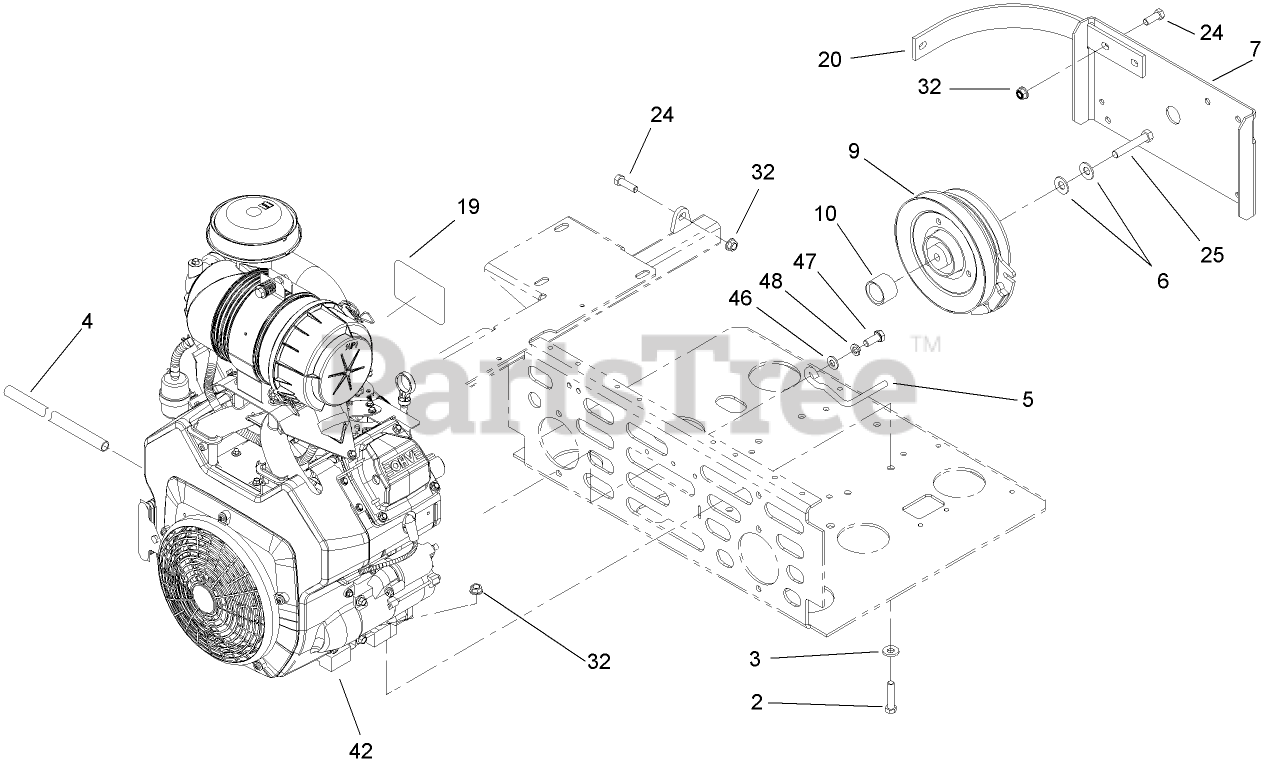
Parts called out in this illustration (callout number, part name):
2	SCREW-HH
3	WASHER-BELLEVILLE
4	TUBE-DRAIN, OIL
5	ROD-BELT
6	WASHER-SPRING
7	GUARD-CLUTCH
9	CLUTCH
10	SPACER-CLUTCH
20	STRAP-GUARD
24	SCREW-HH
25	SCREW-HH
32	NUT-HHF, WHIZ
46	WASHER-FLAT
47	SCREW-HH
48	WASHER-BELLEVILLE
